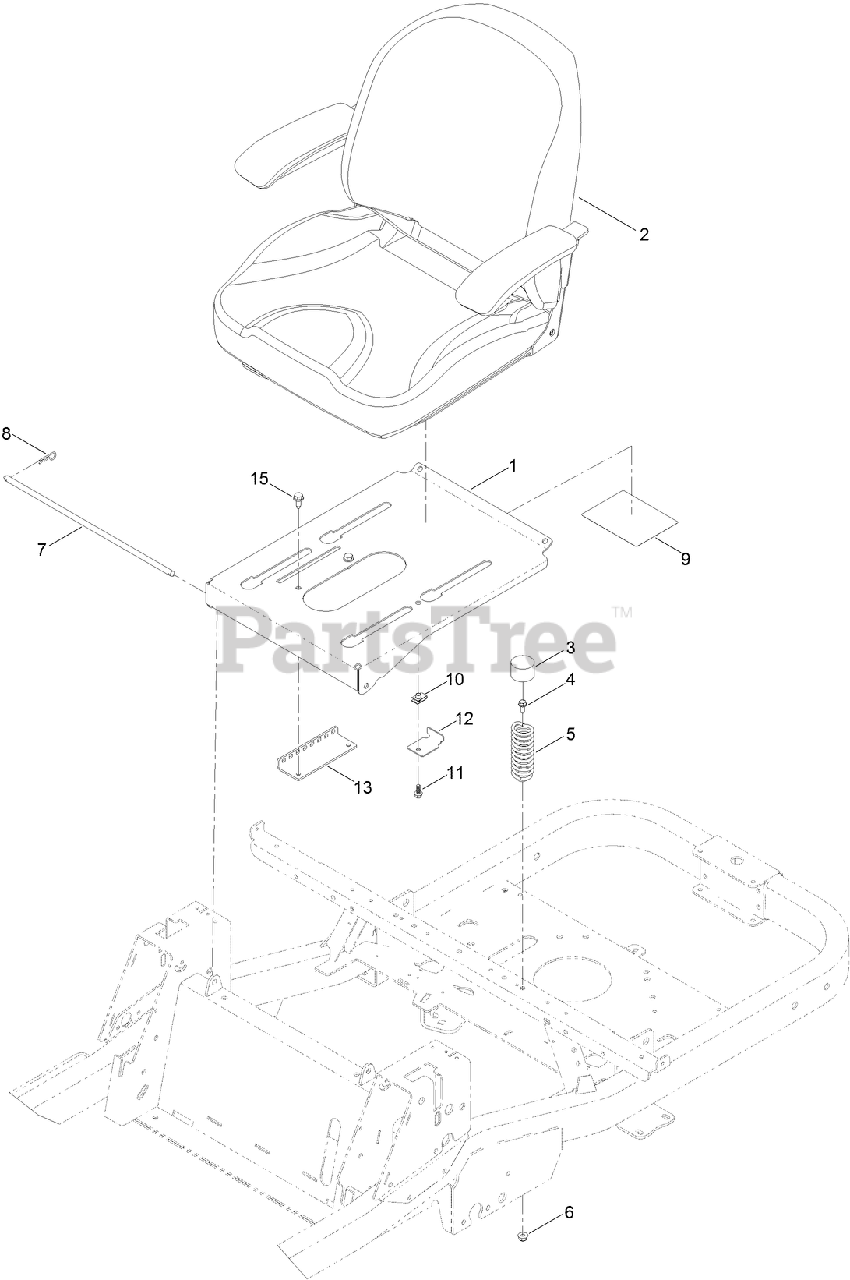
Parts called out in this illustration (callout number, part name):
1	PAN-SEAT
2	SEAT ASM
3	CAP-PROTECTOR
4	SCREW-HHF
5	SPRING-COMPRESSION
6	NUT-HF, NI
7	ROD-STOP
8	PIN-COTTER
9	DECAL-MAINTENANCE
11	SCREW-HHF
12	BRACKET-STOP, SEAT
13	BRACKET-LATCH, SEAT
15	SCREW-HWHTF
